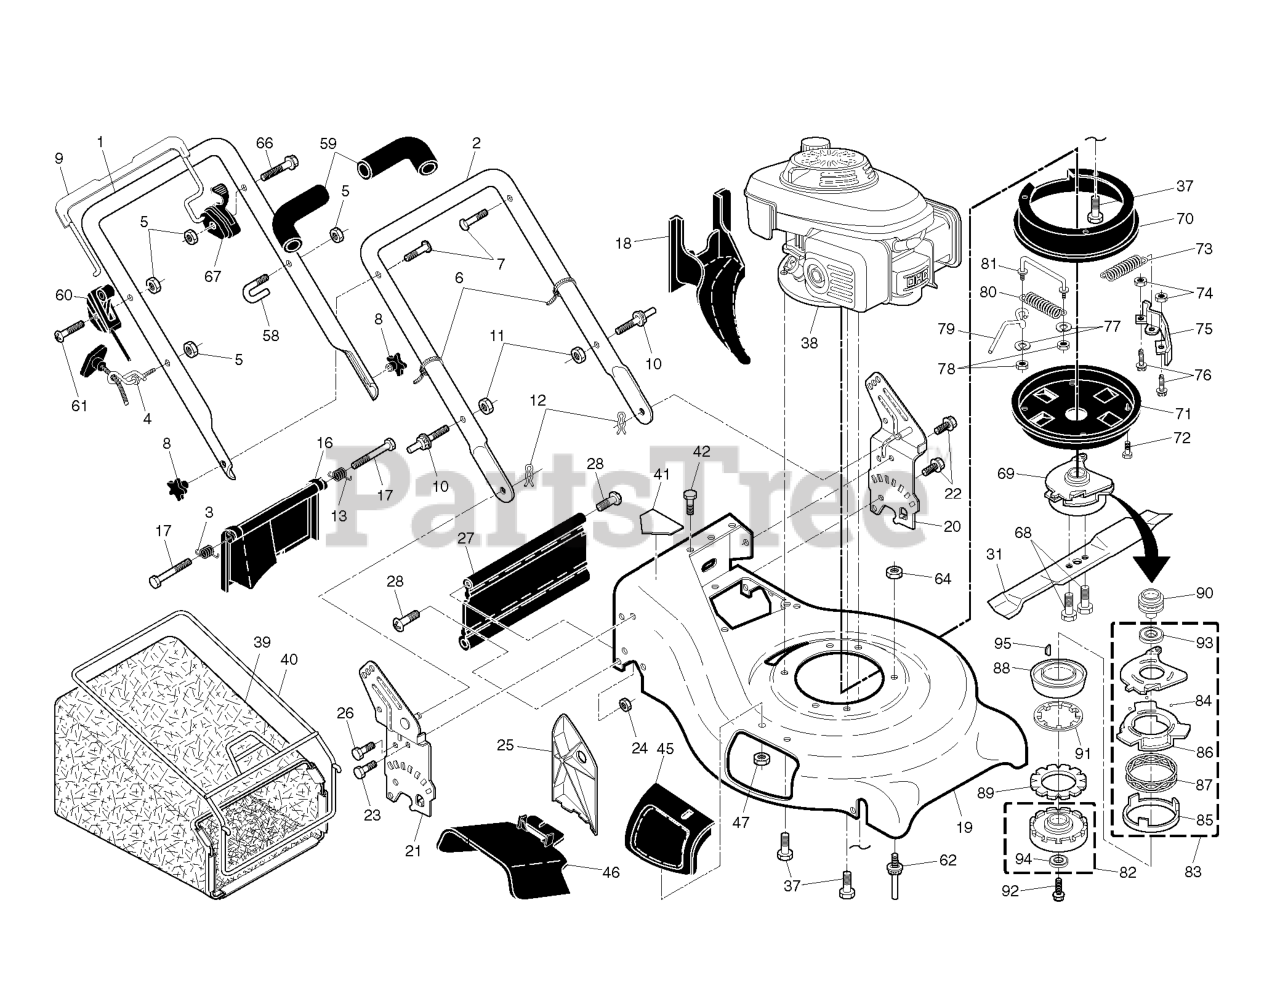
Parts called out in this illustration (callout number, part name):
1	HANDLE.ASM.UPPER.W/GRIP
2	HANDLE.LOWER.21.GREY
3	SPRING.RH.REAR.DOOR.21.RWGD
4	RB GUIDE.ROPE.STD.BLK.ZIN WSL
5	NUT
6	TIE GUIDE
7	BOLT, HANDLE 5/16-18X1.75
8	KNOB.HANDLE.PLASTIC.STAR.BLACK
9	BAIL.CONTROL.HV.BBC.ORANGE
11	NUT.LOCK.5/16-18
12	HAIRPIN COTTER
13	SPRING.LH.REAR.DOOR.21.RWGD
16	REAR DOOR ASSEMBLY
18	PLUG.MULCHER.RGD.21.
19	HOUSING.21.RWD.MC.MS.EZ/ORANGE
20	BRACKET.HNDL.ASM.21.RWGD.LT.OR
21	BRACKET.HNDL.ASM.21.RWGD.RT.OR
22	BOLT.HEX.HD.WASHER.5/16-18X.75
23	BOLT, HEX HEAD 5/16-18
24	NUT.71038.31-18.HEX.NYLOCK
25	CLIPPING DEFLECTOR
27	SKIRT.REAR.21.RWGD.BLACK(2 2M)
28	HINGE SCREW
31	BLADE.21".BBC
37	BOLT 3/8-16X1-1/8
39	RP.GBAG.93230247T.SILV.CROWN.B
40	FRAME.GBAG.21.RWGD.SC
41	DANGER DECAL
42	SCREW 14-20 X 5/8
45	MULCHER DOOR ASM.
46	DEFLECTOR, DISCHARGE
59	GRIP.HANDLE.FOAM.WIDE.(1 SIDE)
60	CONTROL.THROTTLE.HONDA.BBC
62	STUC.GUIDE.BELT.RWGD
64	NUT.HEX.3/8-16
67	CONTROL.BBC.HV.GRY/ORG
68	BOLT.BLADE
70	COVER.BELT.BBC.AW.TOP
71	COVER.BELT
72	TAPPING SCREW
73	SPRING.BBC
74	NUT T
75	BRAKE, CLUTCH
76	BOLT
79	BELT KEEPER
80	SPRING.LINK.BBC
81	LINK.TORQUE.BBC
82	HOLDER.ASM.BLADE.HONDA.
83	BALL.CONTROL.PLATE.ASSY.BBC.MO
84	BALL.STEEL
85	PLATE.SPRING.HOOK
86	PLATE.BRAKE
87	SPRING BALL PLATE
88	DISC.DRIVE
89	DISK.DRIVEN
90	PULLEY.DRIVE.HONDA.
91	SPRING.CLUTCH.HONDA.
92	BOLT.FLANGE
93	BEARING.RADIAL BALL#6006
94	BEARING RAD. BALL#6204
95	KEY.WOODRUFF.16X15.HONDA
